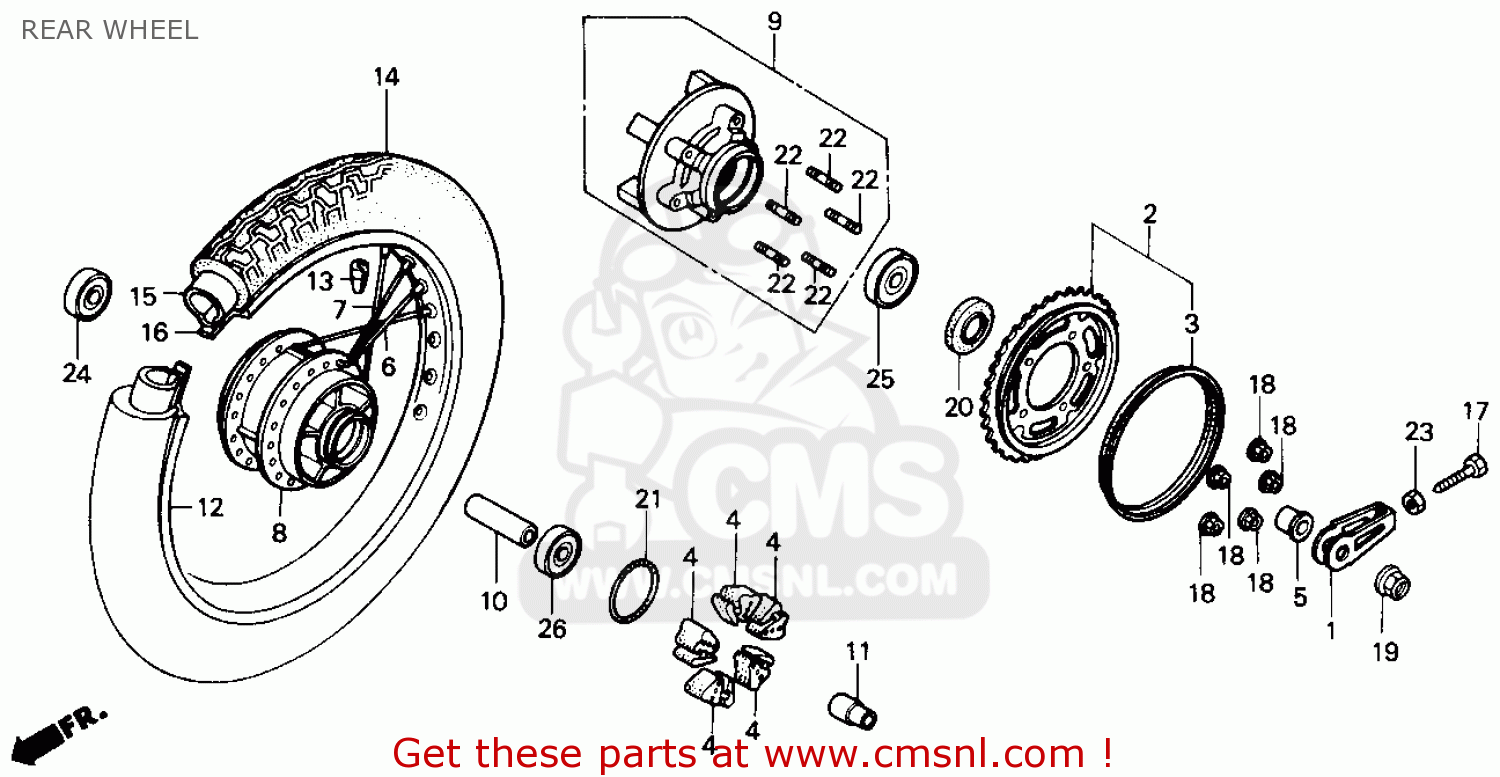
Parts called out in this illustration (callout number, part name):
1	ADJUSTER,CHAIN
2	SPRKT COMP,FINAL
3	ARRESTER,NOISE
4	DAMPER,RR.WHEEL
5	COLLAR,WHEEL SIDE
6	SPOKE SET A,RR.
7	SPOKE SET B,RR.
8	HUB COMP.,RR.
9	FLANGE ASSY.F/DR1
10	COLLAR A,RR.AXLE
11	COLLAR B,RR.DIST
12	RIM,RR.WHEEL (MT2
13	BALANCER (5G)
14	TIRE (110/90-18)
15	TUBE,TIRE
16	FLAP,X-18B
17	BOLT,CHAIN ADJUST
18	NUT,U,FLANGE,10MM
19	NUT,RR.AXLE,16MM
20	OIL,28X47.2X7
21	O-RING,61X2
22	BOLT,STUD,10X45
23	NUT,HEX.,8MM
24	B/BRG RAD N/COM
25	B/BRG RAD N/COM
26	B/BRG RAD N/COM
